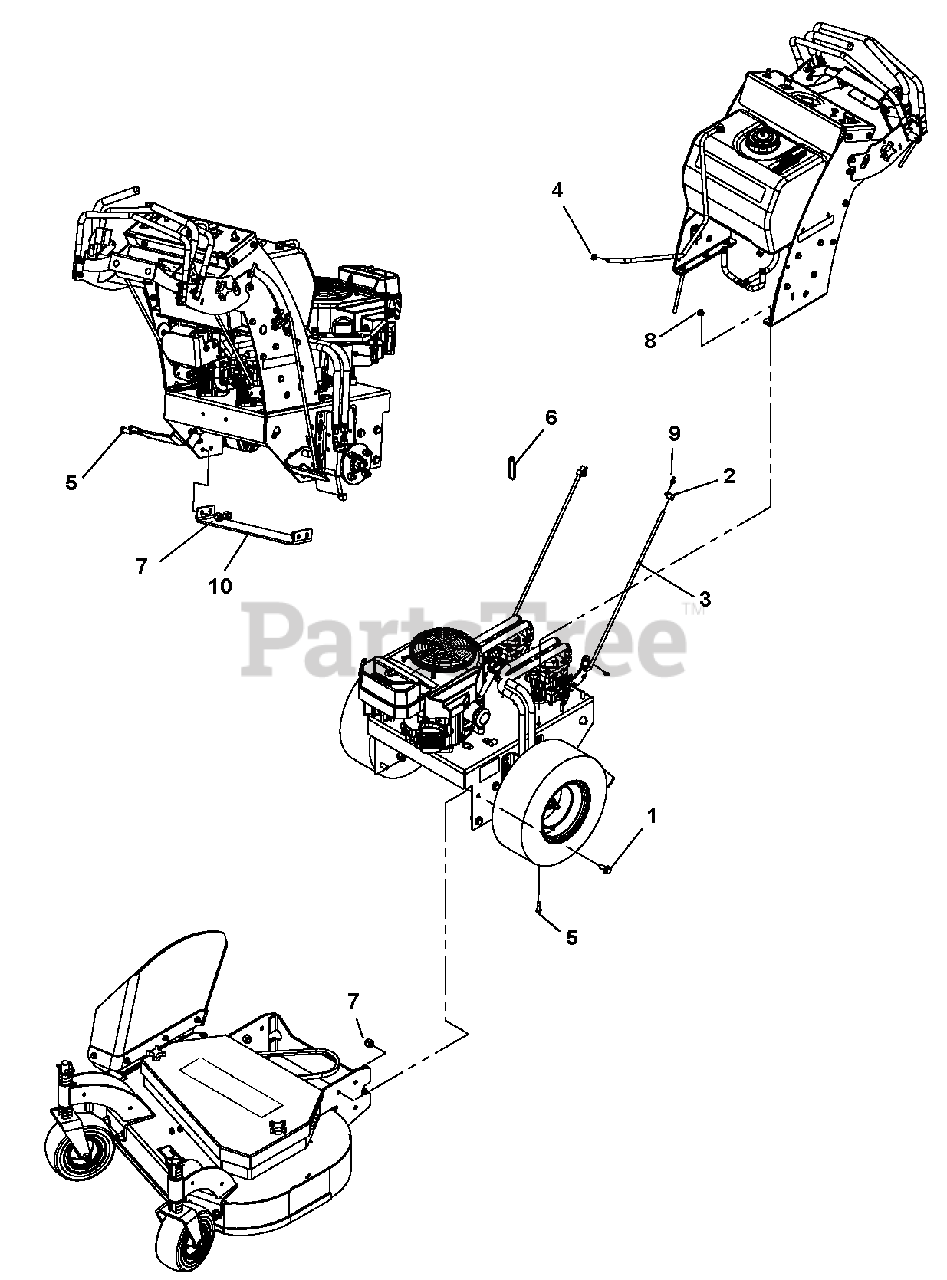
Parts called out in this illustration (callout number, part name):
1	Bolt, .50-13 x 1.25
2	Swivel, .375-24
3	Rod, Drive Control G2FW
4	Clamp, Fuel Line
5	Bolt, .38-16 x 1.25 Hex Grade 5
6	Cable Tie, .15 x 8.50
7	Locknut .50-13 Nyloc
8	Locknut .38-13 Nyloc
9	Ring, Rue .375 x .054 x 1.254
10	Plate, Engine Bed Rear
